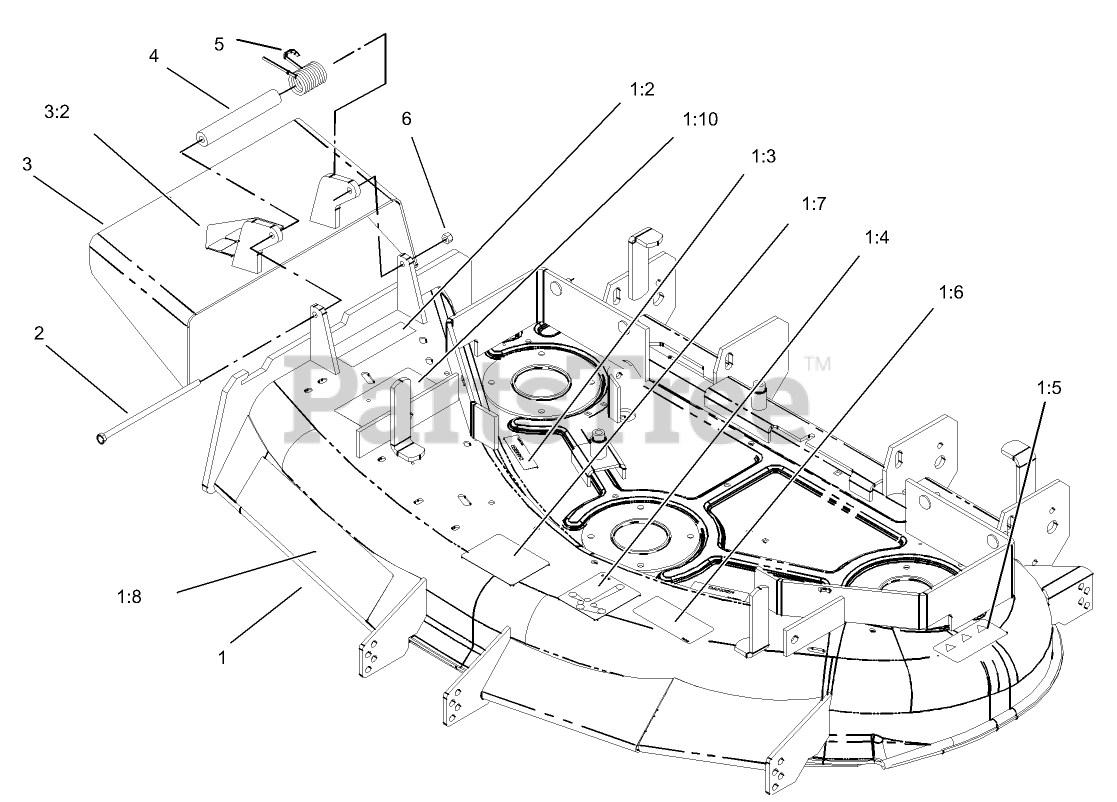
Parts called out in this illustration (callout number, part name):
1	DECK DECAL ASM
1:2	DECAL-WARNING
1:3	DECAL-COVER, MISSING
1:4	DECAL-ROUTING, BELT
1:5	DECAL-DANGER
1:6	DECAL-TORQUE, BLADE BOLT
1:7	DECAL-WHEEL, GAGE
1:8	DECAL
1:10	DECAL-DANGER, THROWN OBJECT
2	SCREW-HH
3	Deflector ASM
3:2	DECAL-DANGER
4	SPACER
5	SPRING-TORSION
6	NUT-LOCK, NI
